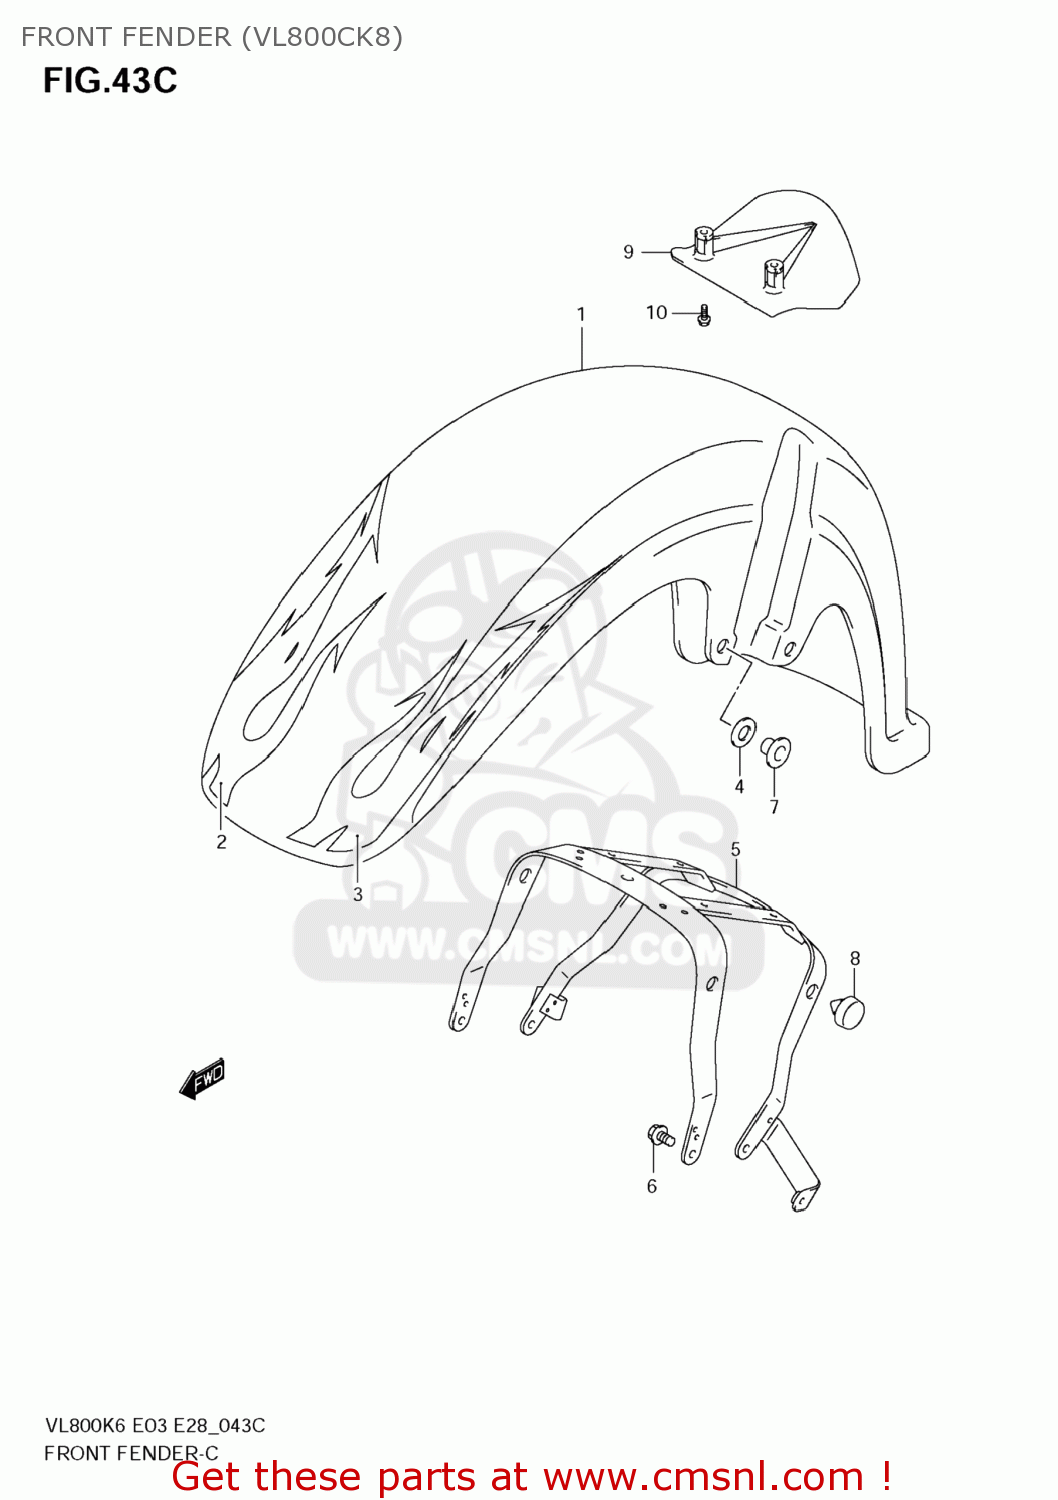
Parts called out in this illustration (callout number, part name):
1	FENDER,FR
2	TAPE,FR FENDER,R
3	TAPE,FR FENDER,L
4	CUSHION,FR FENDER
5	BRACE,FR FENDER
6	BOLT
7	WASHER,FR FENDER
8	CUSHION
9	WING,FR
10	BOLT(6X16)
